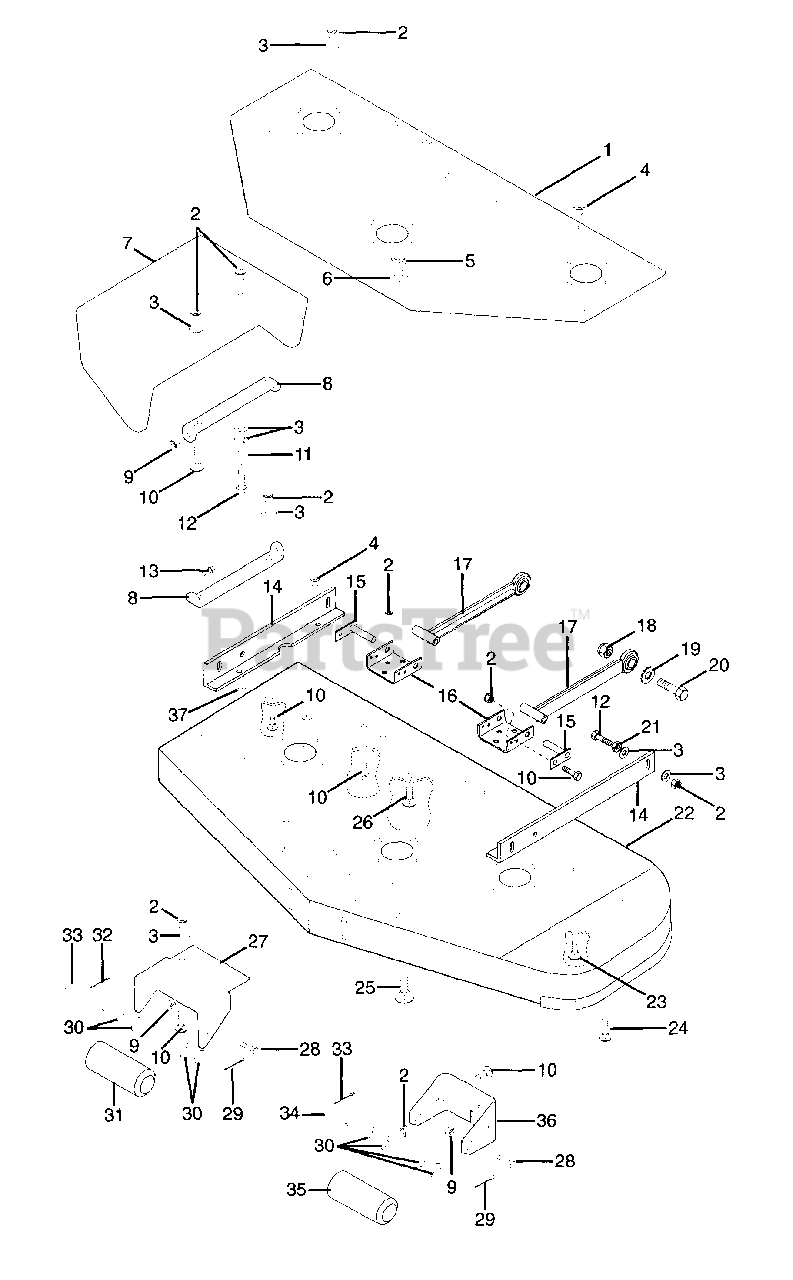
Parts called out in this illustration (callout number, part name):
1	Plate-Support
2	Nut-Locking-Center .375-16
3	Washer-Flat-Steel .406 x .812 x .065
4	Nut-Locking-Center .31-18
5	Nut-Locking-Center .50-13
6	Washer-Flat-Steel .656 x 1.31 x .095
7	Shield-Safety External 50" Mower
8	Bracket-Chute
9	Nut-Locking-Center .25-20
10	Bolt-Round Head Square Neck .38-16 x .75 Grade 2
11	Bushing-Sleeve .407 x .625 x .750
12	Bolt-Hex .38-16 x 1.50 Grade 5
13	Bolt-Hex .25-20 x 1.00 Grade 5
14	Bracket 50" Mower Mounting L.H.
14	Bracket 50" Mower Mounting R.H.
15	Weldment-Mower Mounting Pin
16	Bracket-Mower Mounting Rear
17	Weldment-Mower Mounting Arm
18	Nut-Locking-Center .875-9
19	Washer-Flat-Steel .875 x 1.500 x .1196
20	Bolt-Hex .875-9 x 2.75 Grade 5
21	Nut-Hex .375-16
22	Weldment 50" Mower Fabricated
23	Bolt-Round Head Square Neck .31-18 x .75 Grade 5
24	Bolt-Round Head Square Neck .38-16 x 1.0 Grade 2
25	Bolt-Round Head Square Neck .50-13 x 1.00 Grade 2
26	Bolt-Round Head Square Neck .375-16 x .75 Grade 2
27	Bracket-Roller R.H.
28	Bolt-Hex .25-20 x .75 Grade 5
29	Pin-Center .25 x 2.00
30	Washer-Flat-Steel .656 x 1.312 x .095
31	Roller-Gage
32	Pin-Center .25 x 1.00
33	Shaft-Center Roller
34	Rod
35	Roller-Gage
36	Bracket-Roller
37	Bushing .406 x .750 x .188
